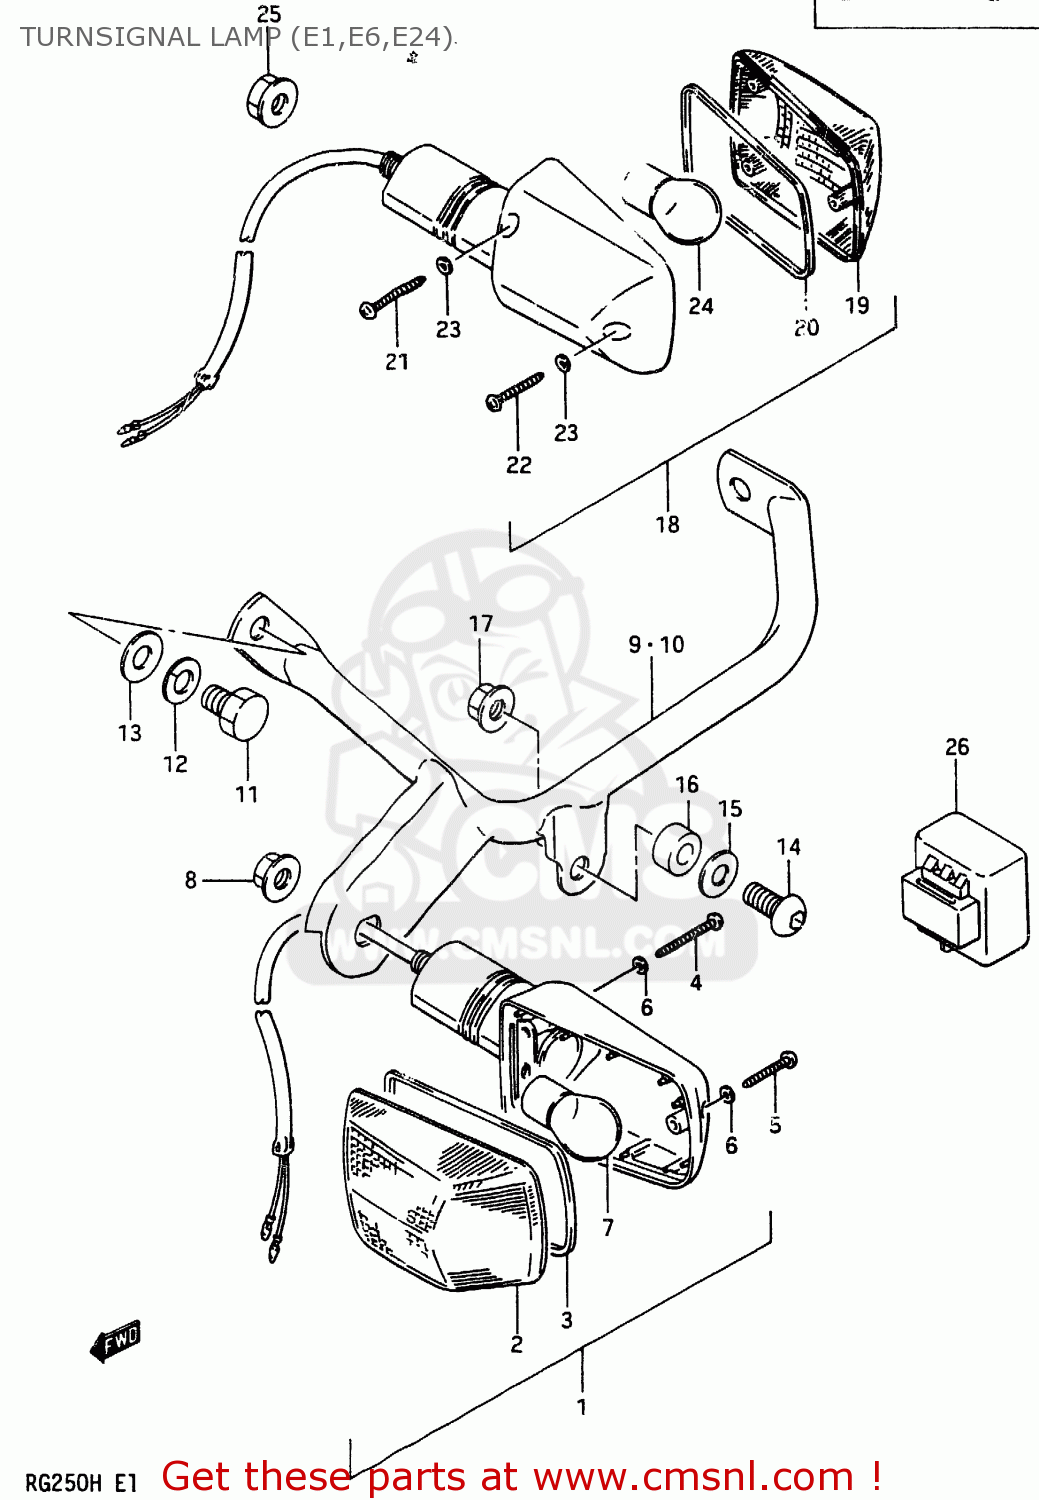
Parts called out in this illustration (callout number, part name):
1	LAMP ASSY,RR TURNSIGNAL
2	LENS
3	GASKET (NAS)
4	SCREW(3X30)
5	SCREW
6	GASKET (NAS)
7	BULB(12V23W,STANLEY,A4577A)
8	NUT
9	BRACKET, FRONT TURNSIGNAL RH
10	BRACKET,FR TURNSIGNAL,L
11	BOLT
12	WASHER,LOCK,8.
13	WASHER
14	SCREW(6X30)
15	WASHER(6.5X16X1.2)
16	SPACER(6.1X8X14.5)
17	NUT
18	LAMP ASSY,RR TURNSIGNAL
19	LENS
20	GASKET (NAS)
21	SCREW(3X30)
22	SCREW
23	GASKET (NAS)
24	BULB(12V23W,STANLEY,A4577A)
25	NUT
26	RELAY ASSEMBLY,TURN SIGNAL
